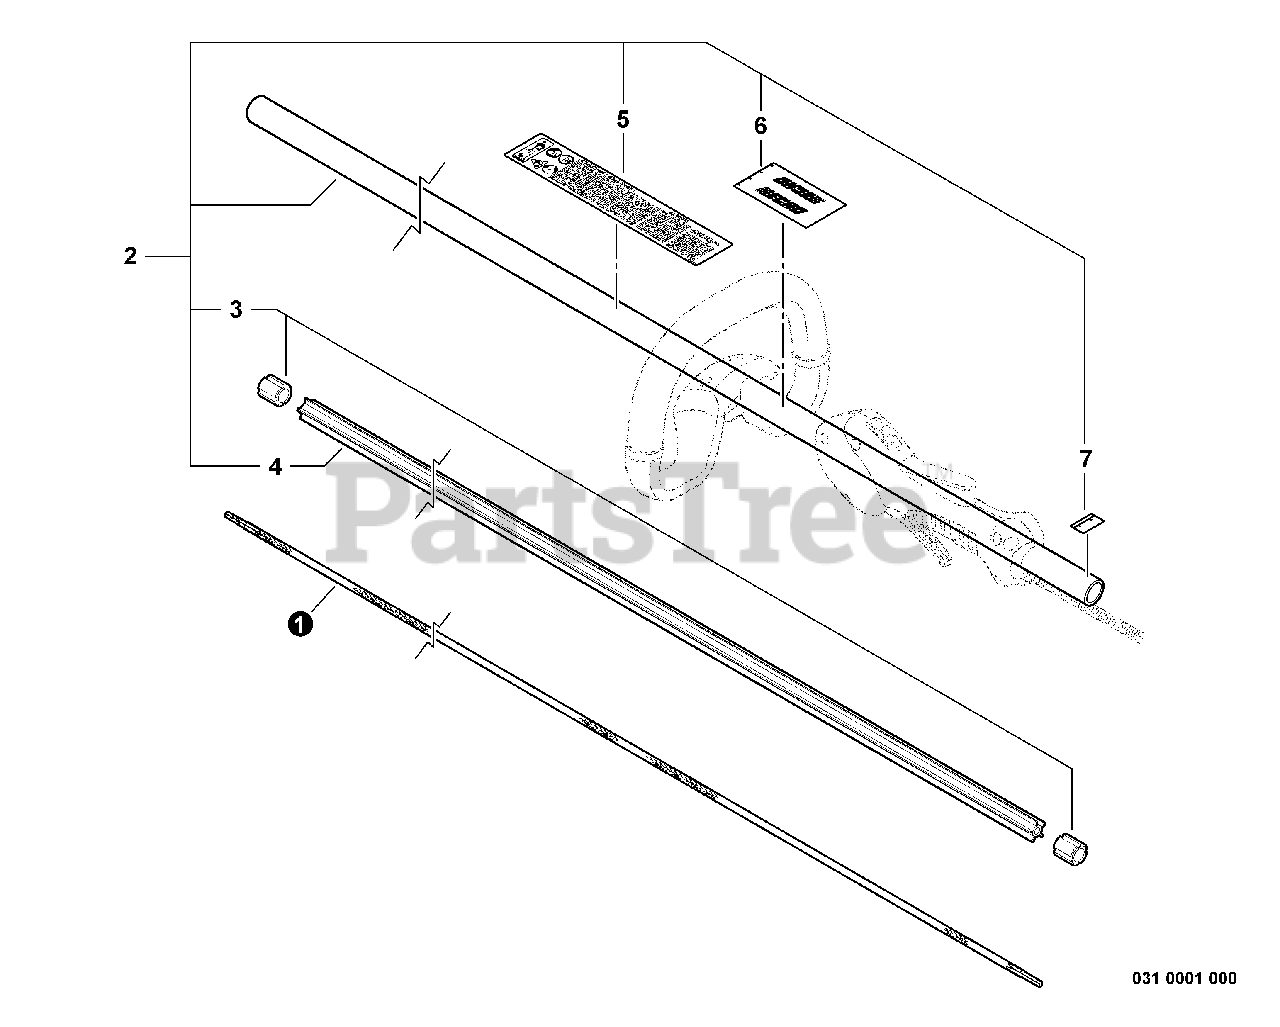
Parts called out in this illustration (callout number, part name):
1	DRIVESHAFT - FLEXIBLE L= 1522
2	MAIN PIPE ASSY
4	LINER, FLEXIBLE 21.6×1420
5	LABEL, CAUTION
6	LABEL, HANDLE LOCATION
7	LABEL - ALIGNMENT
